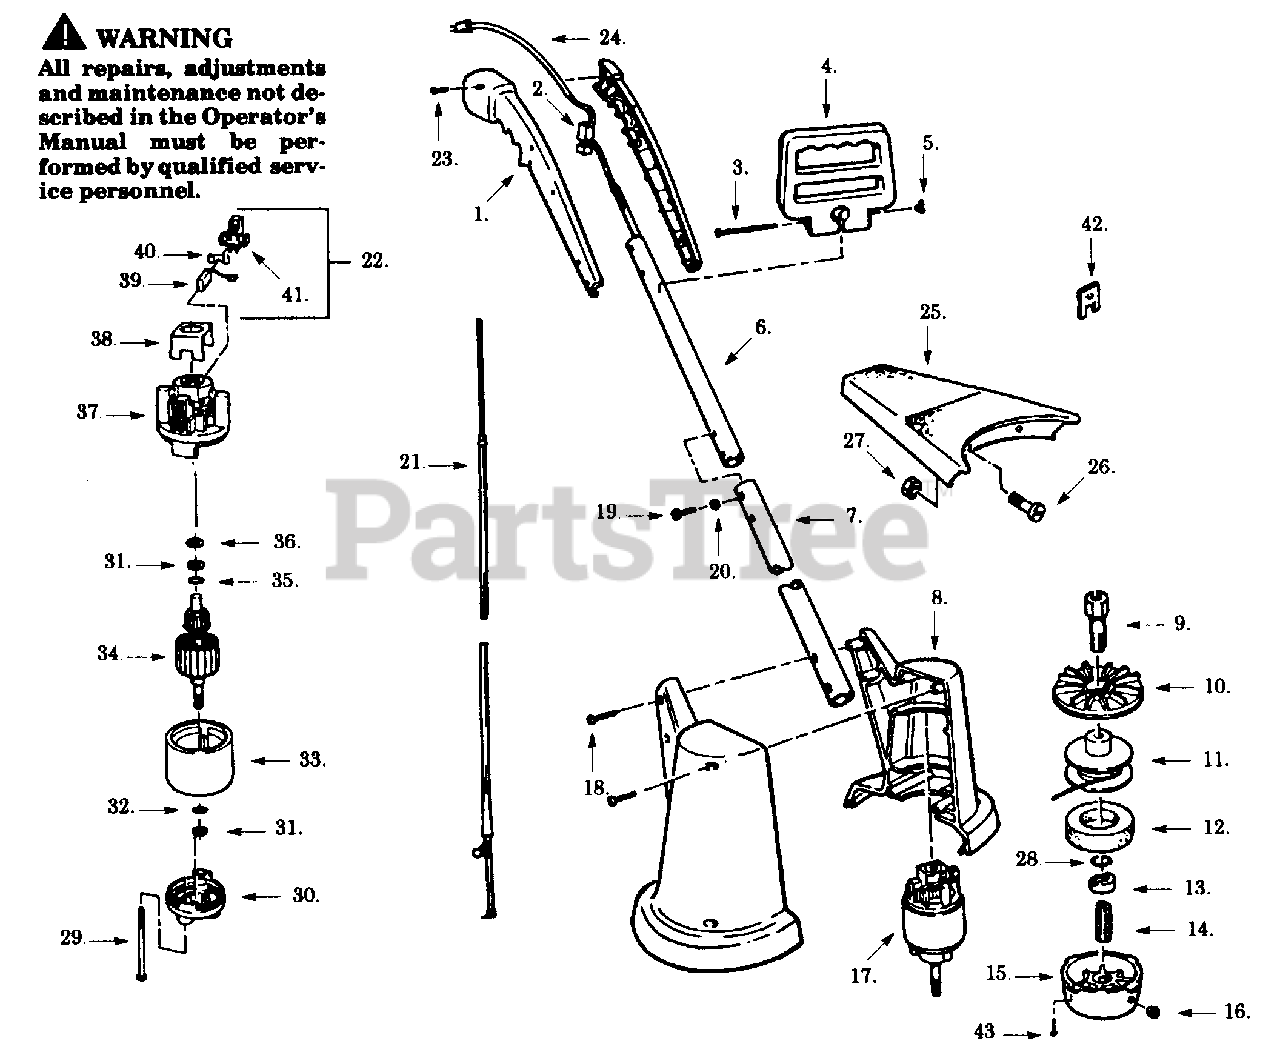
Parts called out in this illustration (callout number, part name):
1	R.H./L.H. Handle
2	Trigger Switch
4	Side Handle
5	Wing Nut
6	Upper Handle Tube
7	Lower Handle Tube
8	R.H./L.H. Housing
9	Drive Adapter Sleeve
10	Rear Plate
11	Spool & Line
12	Foam Pad
13	Drive Adapter Nut
20	Lockwasher
22	Brush Kit (Incl. 39-41)
24	Power Cord
25	Tail Guard
27	Lock Nut
30	Endbell Output
32	Retainer Ring
33	Field Ass'y.
34	Armature
35	Retainer Ring
37	Endbell (Brush)
38	Insulator
40	Brush Spring
41	Brush Holder
42	Spanner Wrench
43	Cotter Pin
